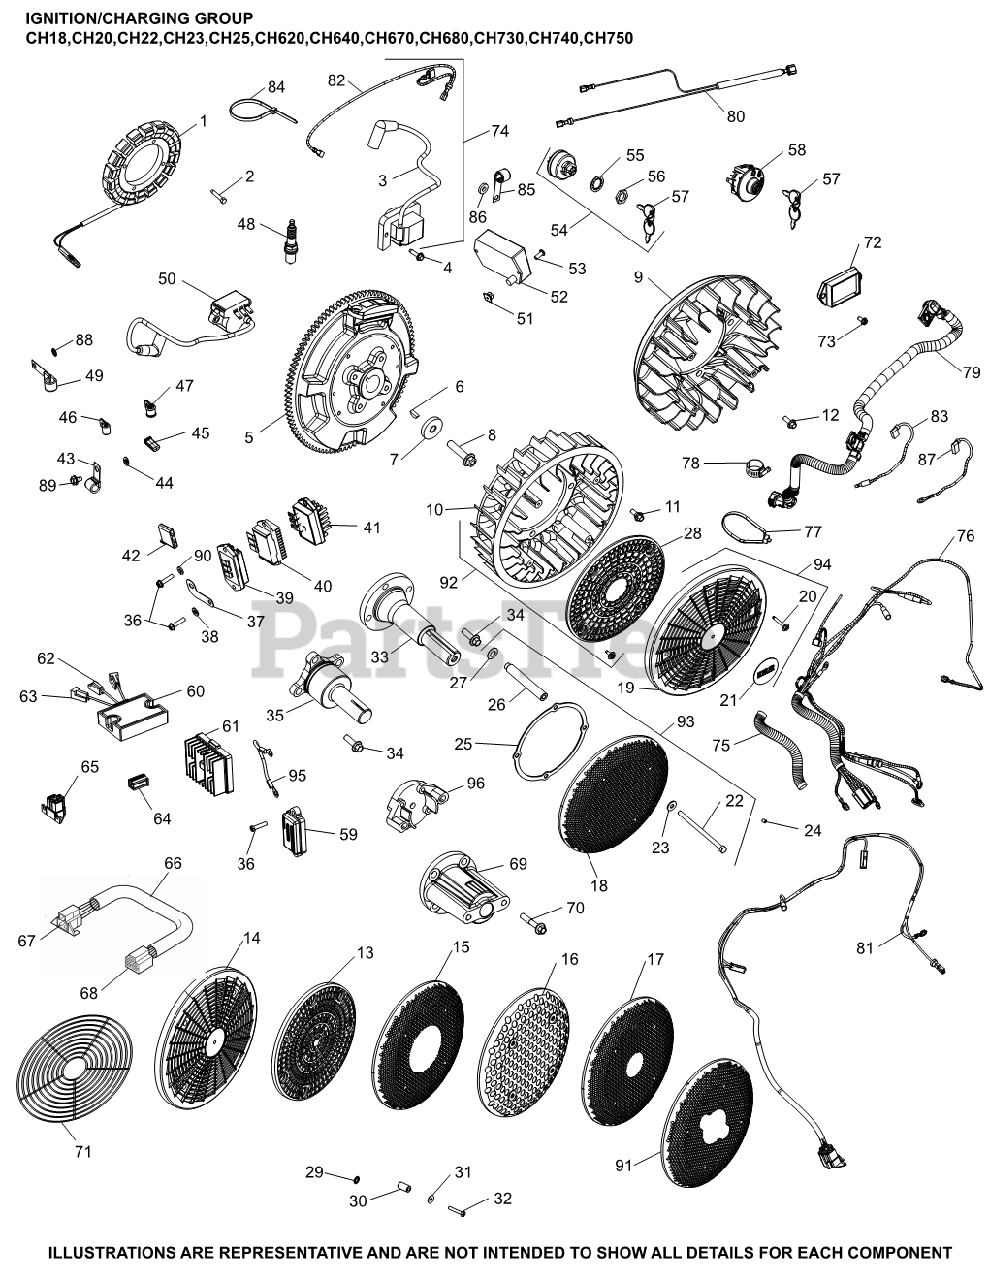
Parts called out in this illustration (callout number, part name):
1	KIT, 15 / 20 AMP STATOR
2	SCREW, THREAD FORMING
3	KIT, MODULE IGNTN (CDI FIXED)
4	SCREW, THREAD FORMING
6	KEY, 3/16" X 5/8"
7	WASHER, FLAT 13/32"
8	SCREW, FLG M10X1.5X45 - (#25086361S)
10	FAN USE 24 755 253-S
11	BOLT, SHOULDER
14	SCREEN, GRASS
20	SCREW, FLG SEMS M4X.7X25
36	SCREW, HEX FLANGE HI-LO
40	REGULATOR, RECTIFIER (20/25 AMP) USE 25 403 32-S
42	CONNECTOR
43	CLIP, CABLE
48	PLUG, SPARK (PRO SERIES)
57	KEY, SET OF 2
58	KIT, KEY SWITCH (SNAP-IN)
76	HARNESS, WIRING ASSEMBLY
82	LEAD, DUPLEX
83	LEAD, OIL SENTRY
87	LEAD, 20/25 AMP B+
90	WASHER, LOCK
94	KIT, GRASS SCREEN
